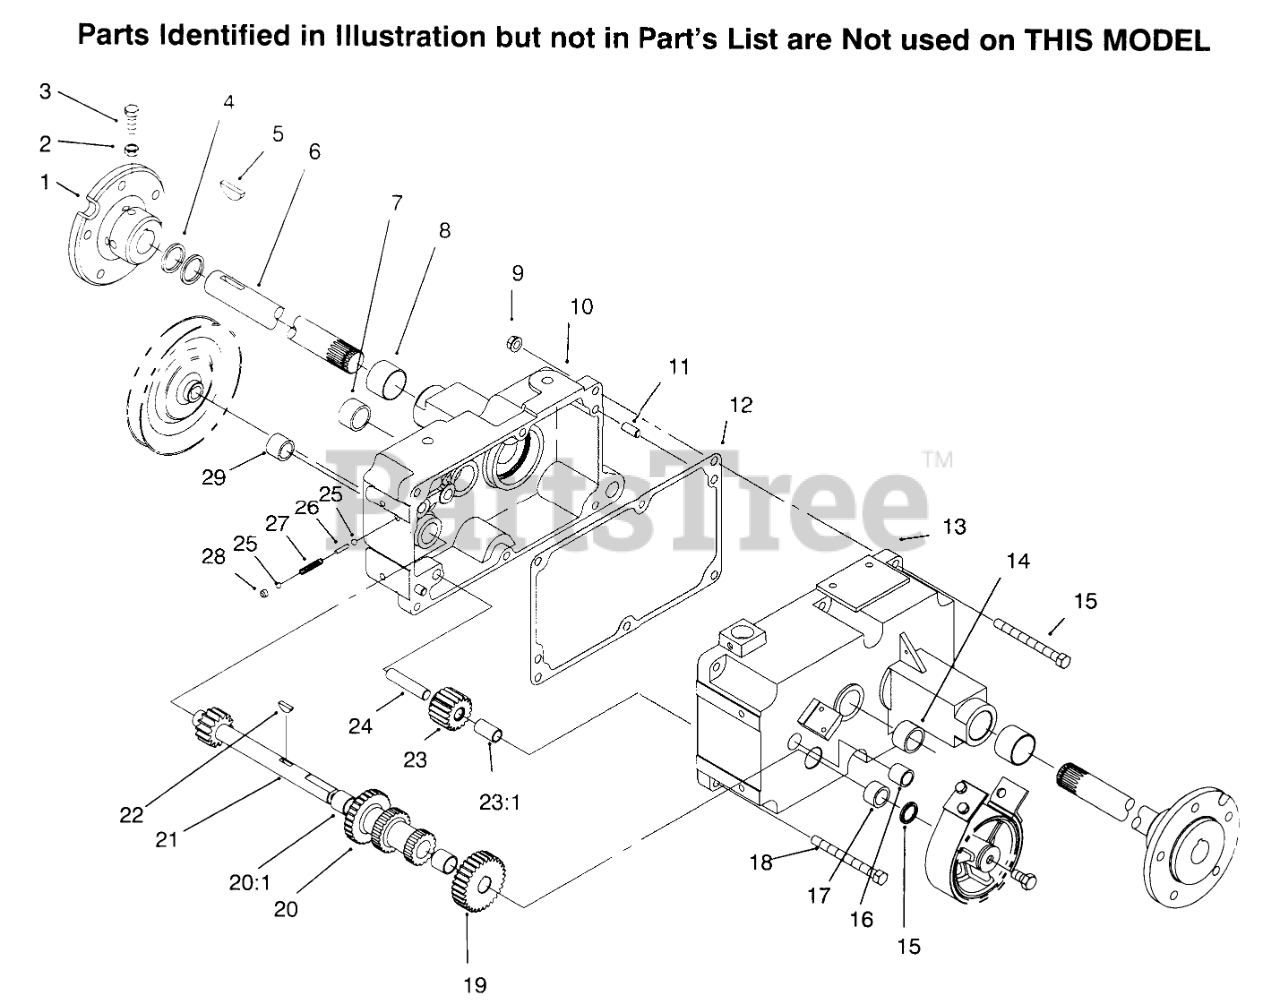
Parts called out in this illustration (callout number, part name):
1	Hub Rear
2	NUT-JAM
3	SCREW-SET, SQH
4	SEAL-OIL
5	KEY-WOODRUFF
6	AXLE-REAR
7	BEARING-NEEDLE
8	BEARING
9	NUT-LOCK, NI
9:9	PINION SHAFT
10	Case Trans RH
11	PIN-DOWEL
12	GASKET-TRANSMISSION
13	Case Trans LH
14	SCREW-HH
15	SEAL-OIL
16	SCREW-HH
16	BEARING-NEEDLE
17	BEARING-NEEDLE
19	SHIFT FORK ASM
19	GEAR-CLUSTER SHAFT
19	Shift Fork
20	GEAR-CLUSTER
20:1	BUSHING-BRONZE
21	SHAFT-CLUSTER
23	GEAR/BUSHING ASM-REVERSE IDLER
23	Gear-Spur
23:1	BUSHING
24	PIN-DIFFERENTIAL
24:1	Shift Lever
24:2	Shaft-Lever
26	PIN-SHIFT
27	SPRING-SHIFT STOP
28	CUP-PLUG
29	BEARING-NEEDLE
56	GEAR-SLIDING
